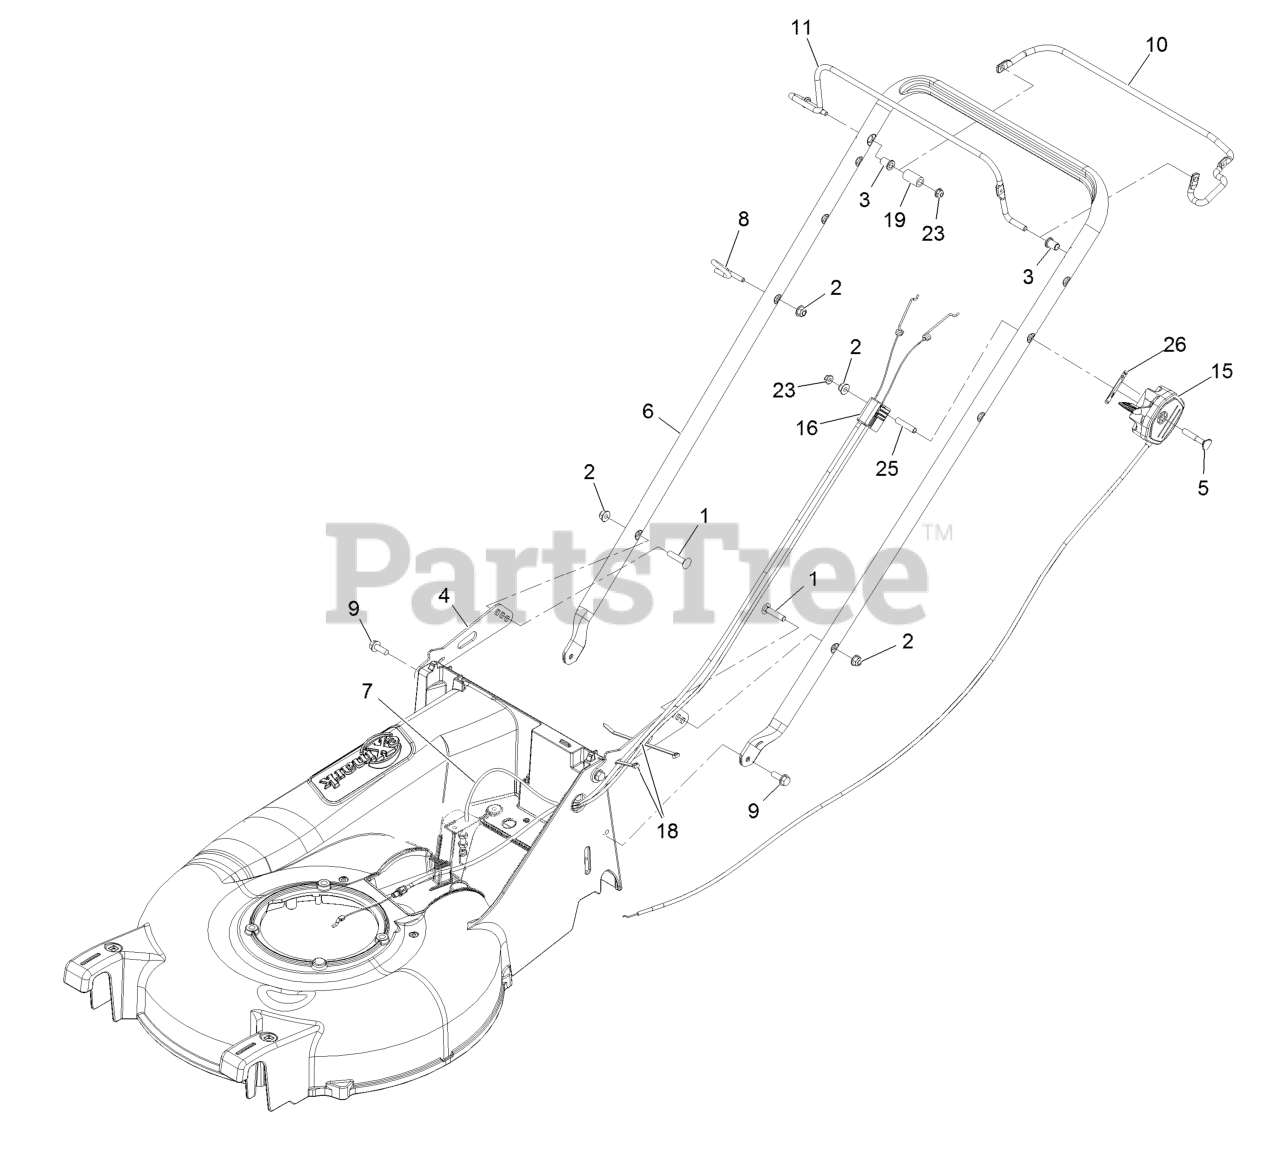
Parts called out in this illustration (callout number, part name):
1	Bolt-Carriage 5/16-18 X 1 1/2
2	Nut-Nyloc 5/16-18 Flg
3	Bushing-Handlebar
4	Bracket,Handlebar
5	Screw-HH
6	Handlebar-P21
7	Cable, Drive Ec21
8	Guide,Rope
9	Screw-HWH 3/8-16 X 7/8 Taptite
10	Bail-Drive Coated
15	Cable-Throttle/Choke
16	Cable-Zone Honda
18	Tie-Cable
23	Nut-Nyloc 1/4-20 Flg
25	Spacer-Throttle
26	Decal, Throttle/Choke
